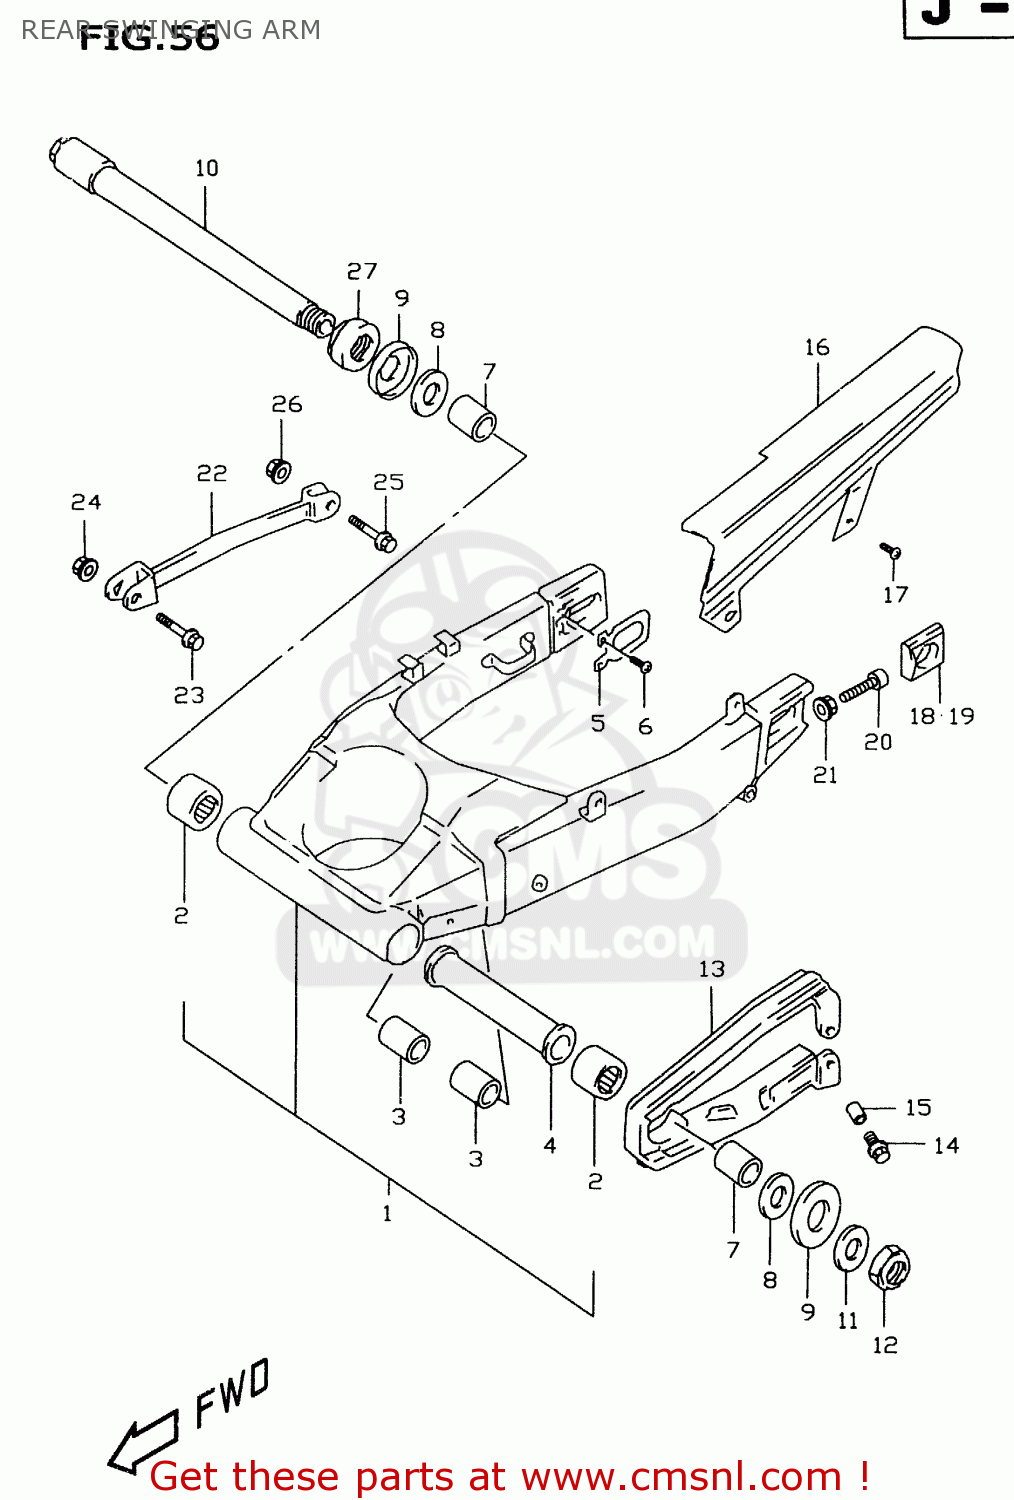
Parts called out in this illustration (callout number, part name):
1	SWINGINGARM ASSY,RR
2	BEARING(30X40X25)
3	BEARING(17X24X20)
4	SPACER COMP,REAR SWING PIVOT
5	PLATE,RR SWING ARM BRKT
6	SCREW 6X10
7	SPACER,REAR SWING ARM PIVOT
8	WASHER
9	DUST SEAL,RR SWGARM PIVOT
10	SHAFT,RR SWINGINGARM PIVOT
11	WASHER(25.2X42X3.2)
12	NUT
13	BUFFER,CHAIN TOUCH DEFLECTOR
14	BOLT 6X20,WITH PLAIN WASHER
15	SPACER(6.5X9X5)
16	CASE,CHAIN
17	SCREW(6X16)
18	ADJUSTER,CHAIN,R
19	ADJUSTER,CHAIN,L
20	BOLT(8X50)
21	NUT
22	TORQUELINK,RR
23	BOLT
24	NUT
25	BOLT(10X37)
26	NUT
27	NUT,REAR SWING ARM PIVOT
